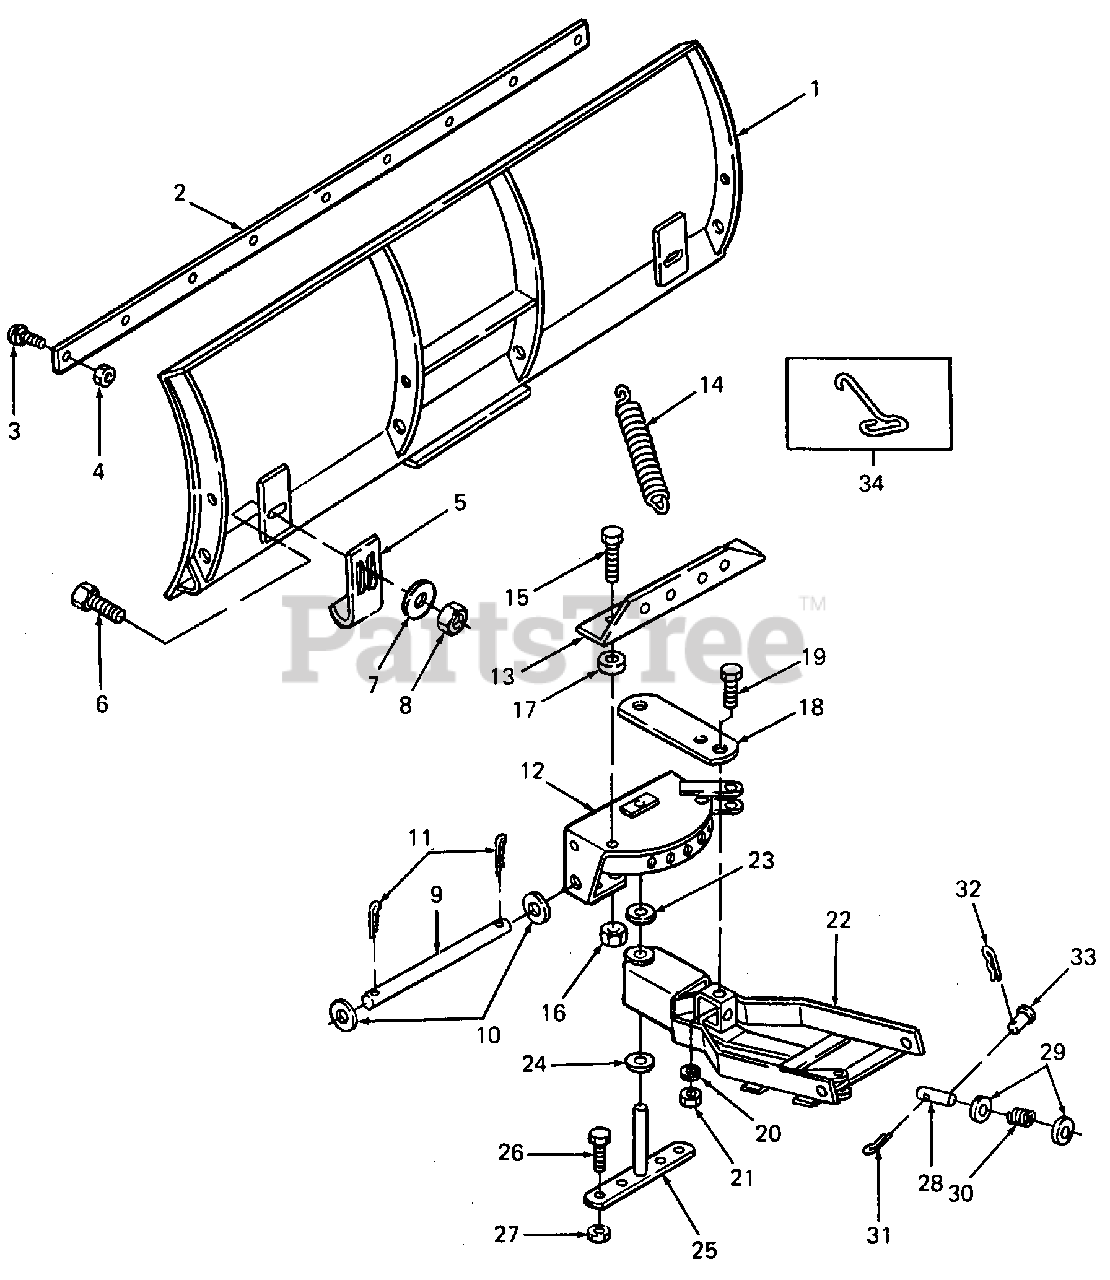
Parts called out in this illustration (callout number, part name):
1	Snowblade - 54 Inch
2	Edge, Blade Cutting
3	Bolt, Sq Neck Carriage, 5/16-18 X 1.0 Lg
4	Nut, Hex Flange Lock, 5/16-18
5	Shoe, Skid
6	Bolt, Sq Neck Carriage, 3/8-16 X 1.0 Lg
7	Washer, Flat, 7/16 X 1.0 X .08 Thk
8	Nut, Hex Flange, 3/8-16
9	Pin, Locating
10	Washer, Flat, .812 X 1.46 X .108 Thk
11	Pin, Cotter, 1/8 Dia X 1.25 Lg
14	Spring, Brakeover
15	Screw, Hex Cap, 1/2-13 X 1.5 Lg GR5
16	Nut, Hex Center Lock, 1/2-13
17	Spacer, Pivot Stop
19	Screw, Hex Cap, 1/2-13 X 1.25 Lg GR5
20	Washer, Lock, 1/2
21	Nut, Hex, 1/2-13
22	"A" Frame Assembly
23	Washer
24	Washer, Flat, .812 X 1.46 X .108 Thk
25	Pin, Pivot
26	Screw, Hex Cap, 1/2-13 X 1.25 Lg GR5
27	Nut, Hex Center Lock, 1/2-13
28	Pin, Lock
29	Washer, Flat, 21/32 X 1-5/16 X .095 Thk
31	Pin, Cotter, 1/8 Dia X 1.25 Lg
32	Pin, Quick Attach
33	Pin, Clevis
34	Hook, Spring Mounting
